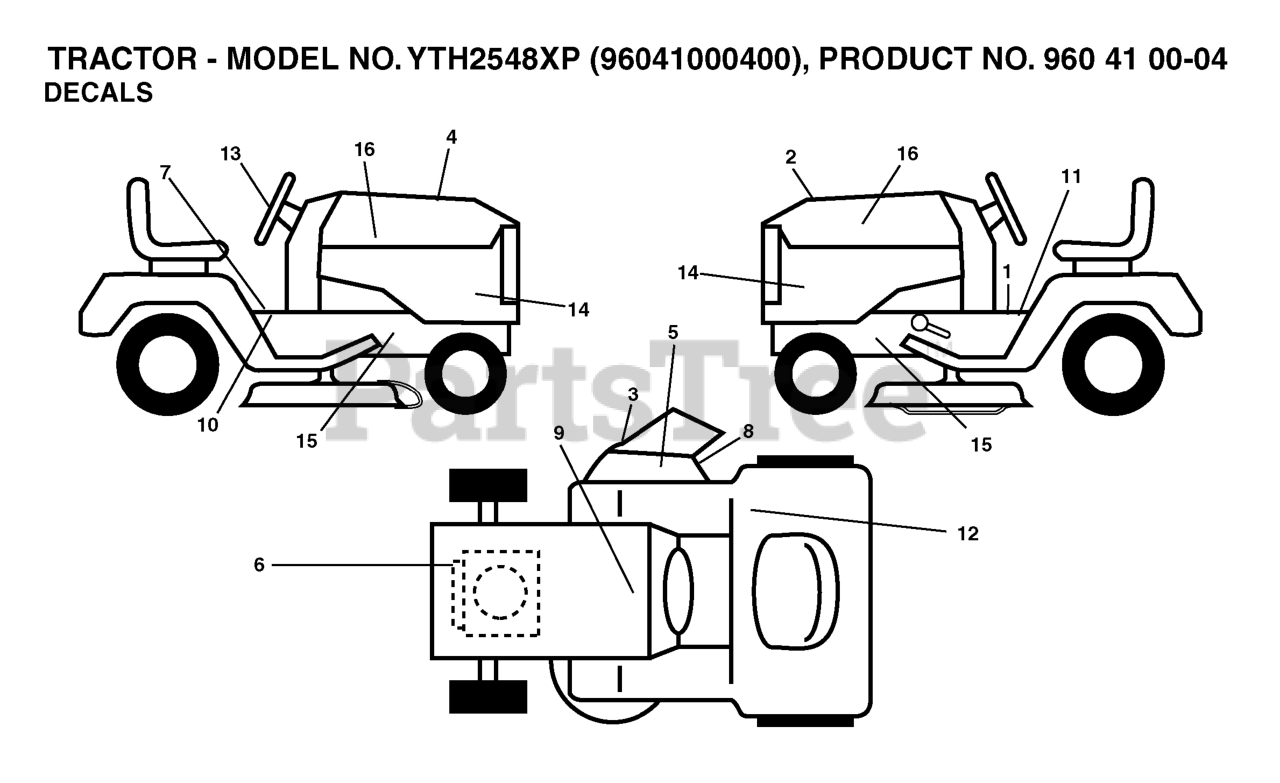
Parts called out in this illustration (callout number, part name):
1	DECAL
2	DECAL.HOOD.TOP.INSERT.
3	DECAL, DEFLECT WARNING
4	DECAL HOOD CUST. RESP.
5	DECAL.INTERNATIONL.CUTFINGER
6	DECAL
7	DECAL PARK BRAKE
8	DECAL.MOWER.SCH.48/54
9	DECAL BTRY SYMBOLS
10	DECAL
11	LABEL
12	DECAL
13	DECAL.STEERING.HUSQ.BLUE
16	DECAL.HOOD.NAMELOGO.HUSQ
